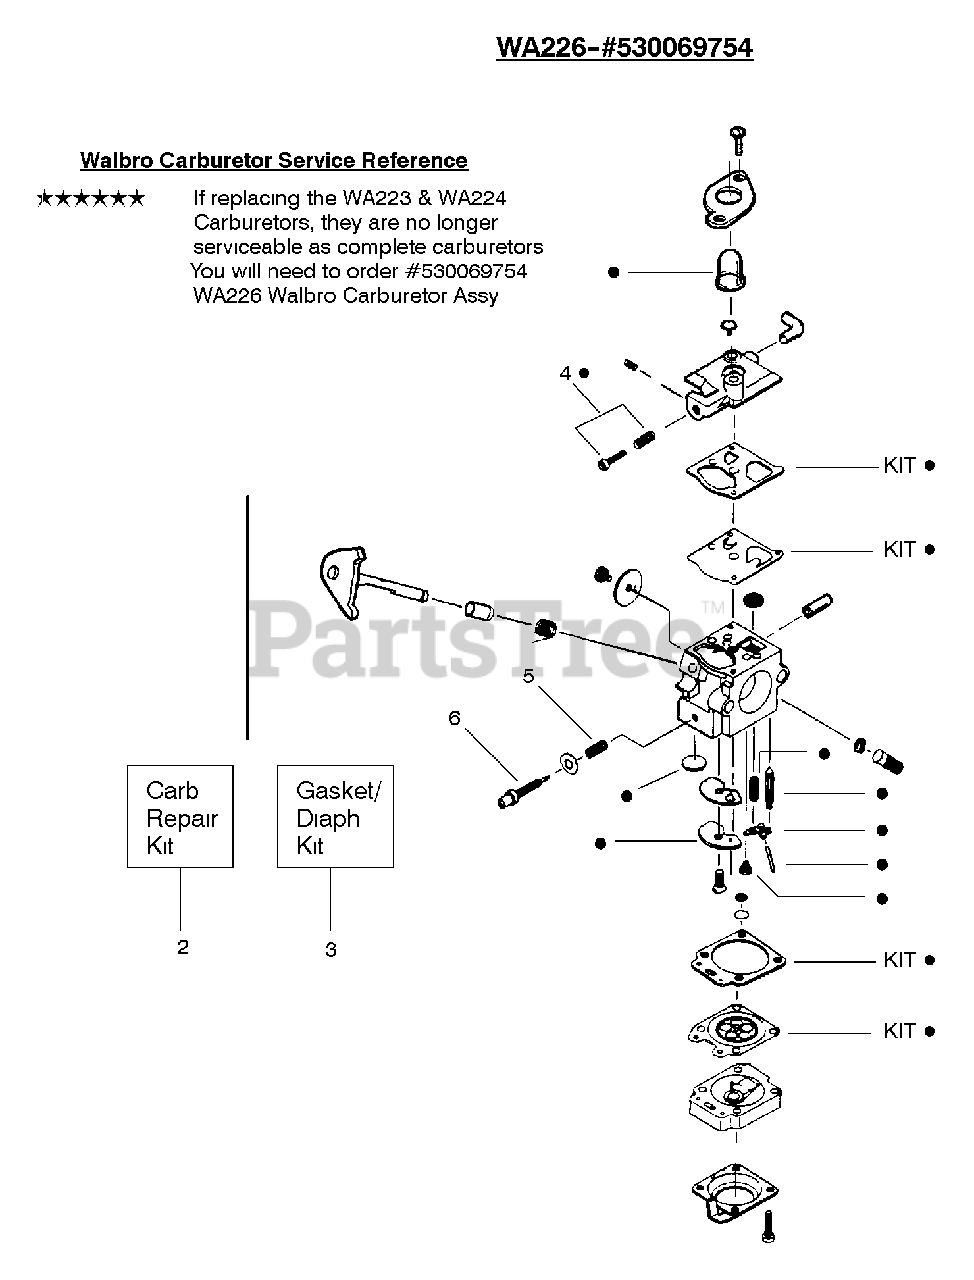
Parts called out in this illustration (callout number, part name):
2	Carburetor Repair Kit WA226
3	Gasket/Diaphragm WA223, WA224 & WA226
4	Idle Screw & Spring Kit
5	Low Speed Spring
6	Low Speed Needle
530069754	Carburetor Assembly (WA226)
